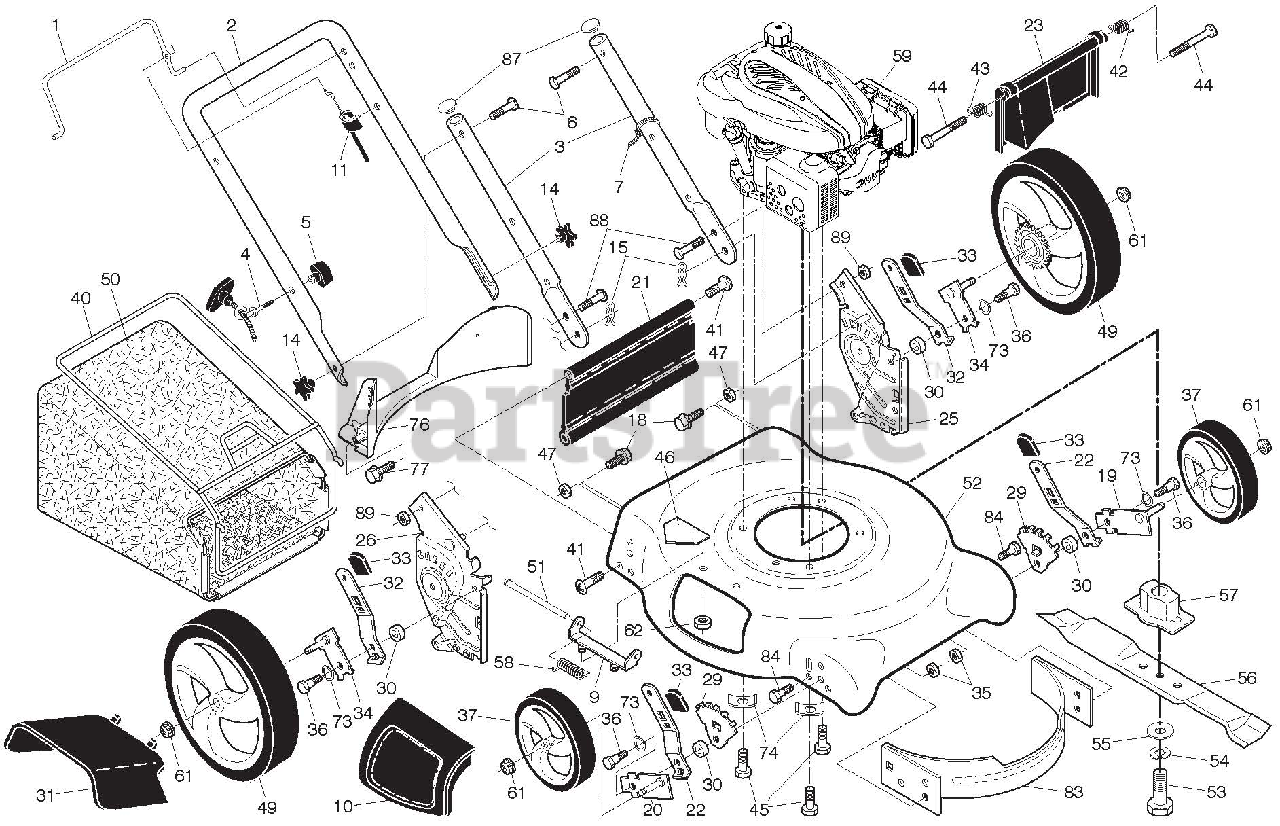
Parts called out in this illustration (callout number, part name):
1	CONTROL BAR
2	UPPER HANDLE
3	BAR, LOWER HANDLE
4	ROPE GUIDE
6	Handle Bolt
7	Wire Tie
8	Bolt, Hex Head 5/16-18 x 3/4
9	Handle Bolt
10	Mulcher Door
11	ENGINE ZONE CONTROL CABLE
14	Handle Knob
15	Ring, Klip
18	SCREW.HEX.WASHEAD.1/4-20 X 3/8
19	AXLE ARM ASSEMBLY, FRONT, LH
20	AXLE ARM ASSEMBLY, FRONT, RH
21	Kit, Rear Skirt
22	SELECTOR SPRING, FRONT
23	REAR DOOR ASSEMBLY
25	HANDLE BRACKET, LH
26	HANDLE BRACKET, RH
29	WHEEL ADJUSTING BRACKET
31	Discharge Deflector
32	SELECTOR SPRING, REAR
33	Selector Knob
34	AXLE ARM ASSEMBLY, REAR
35	Locknut, Hex 5/16-18
36	Shoulder Bolt
37	WHEEL & TIRE, FRONT, 8 X 1-3/4
39	Flanged Locknut, Hex
40	Frame, Grassbag
41	HINGE SCREW
42	Spring, Rear Door, LH
43	Spring, Rear Door, RH
44	Bolt, Rear Door
45	Screw, Hex Head, Threaded, Rol
46	DECAL, WARNING
47	Nut, Hex
49	WHEEL & TIRE, REAR, 11 X 1-3/4
50	GRASSBAG
51	Hinge Rod
52	KIT, HOUSING
53	Screw, Hex Head, Grade 8 3/8-2
54	Helical Lockwasher
55	Hardened Washer
56	21" Blade
57	BLADE ADAPTER
58	Hinge Spring
59	ENGINE,LNCN T322002896-2131008
61	Nut, Hex, Flangelock 3/8-16
62	Lock Nut 1/4-20
65	Washer, Flat
73	Washer, Curved, Cylindrical
74	WASHER, SPECIAL, ENGINE
76	BAFFLE, REAR
77	Screw, Rear Baffle
83	BAFFLE, FRONT
84	BOLT.5/16-18HEX.WHS.HD.LCKSERR
87	PLUG, HANDLE BAR
88	BOLT, CARRIAGE
89	Nut, Hex, Flangelock
